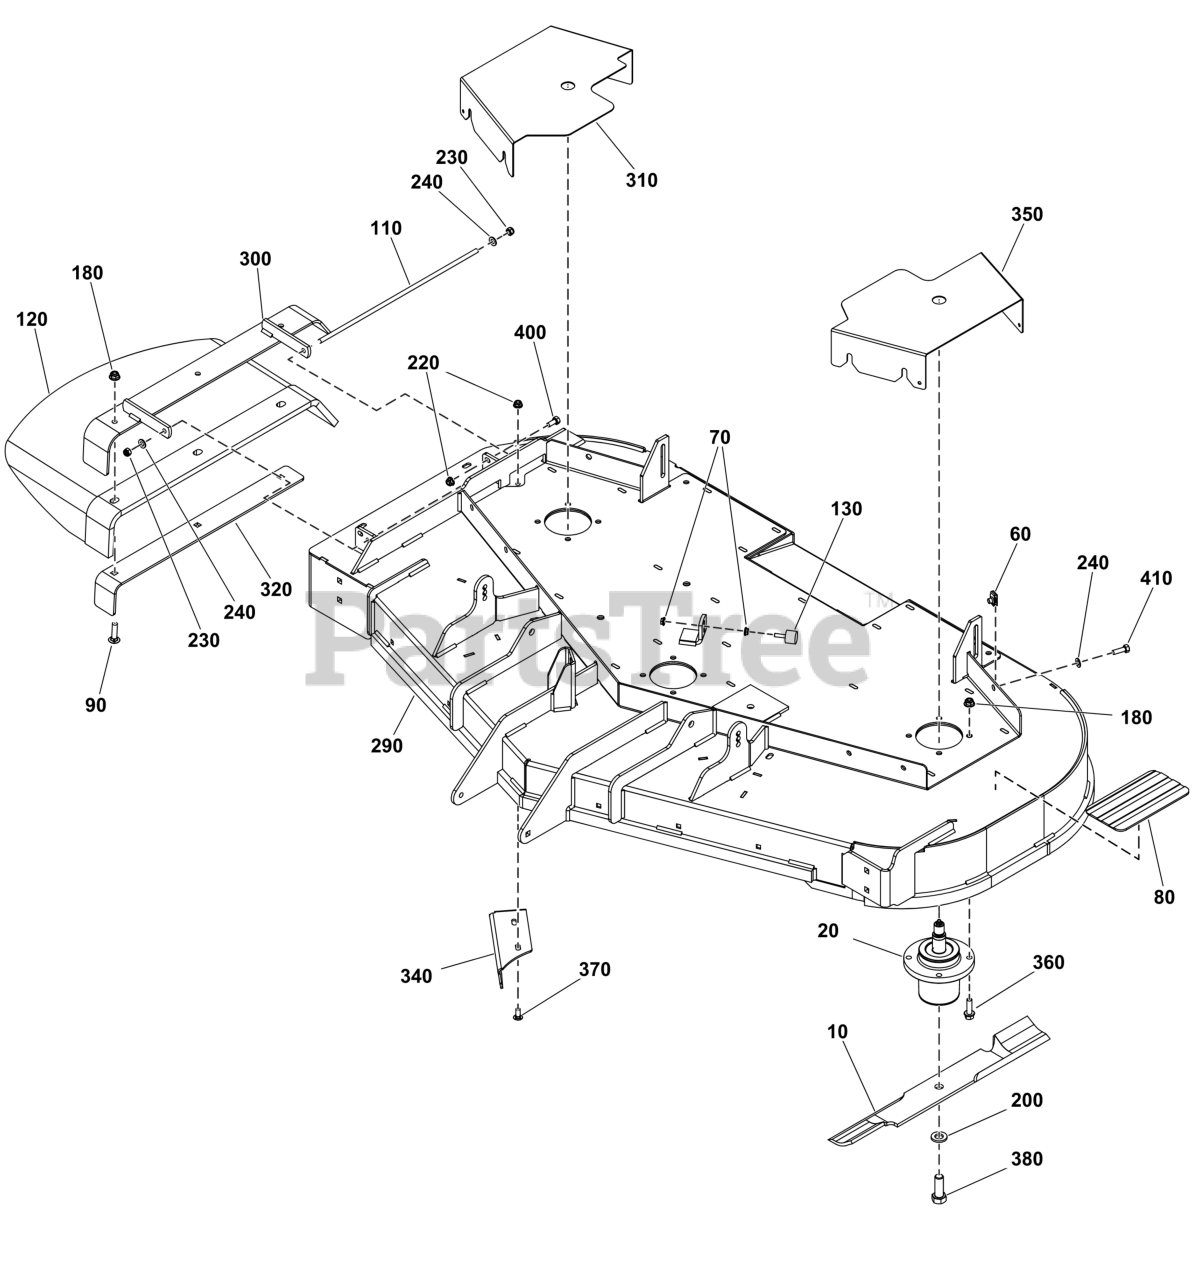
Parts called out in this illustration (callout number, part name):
10	BLADE SET, 61 DECK (3)
20	SPINDLE ASSEMBLY
60	BODY CLIP, 5/16-18 X
80	SAFETY WALK
90	BOLT, 3/8-16 X 1-1/2
110	ROD
120	CHUTE, RUBBER DISCHARGE (5104442)
180	NUT, 3/8-16 HEX NYLOCK
200	WASHER, 5/8" YZ
220	NUT
230	NUT, 5/16-24 HEX NYLO
240	WASHER
290	DECK SHELL W/DECALS, 700-60 USA,5423241B
290	DECK SHELL W/DECALS, 700-60 EXP,5423241B
300	FRAME, Chute
310	PLATE, Guard, Right
320	PLATE, SUPPORT
340	DEFLECTOR
350	PLATE, Guard, Left
370	BOLT, 5/16-18 X 3/4",
380	BOLT
400	BOLT, 5/16-18 X 3/4"
